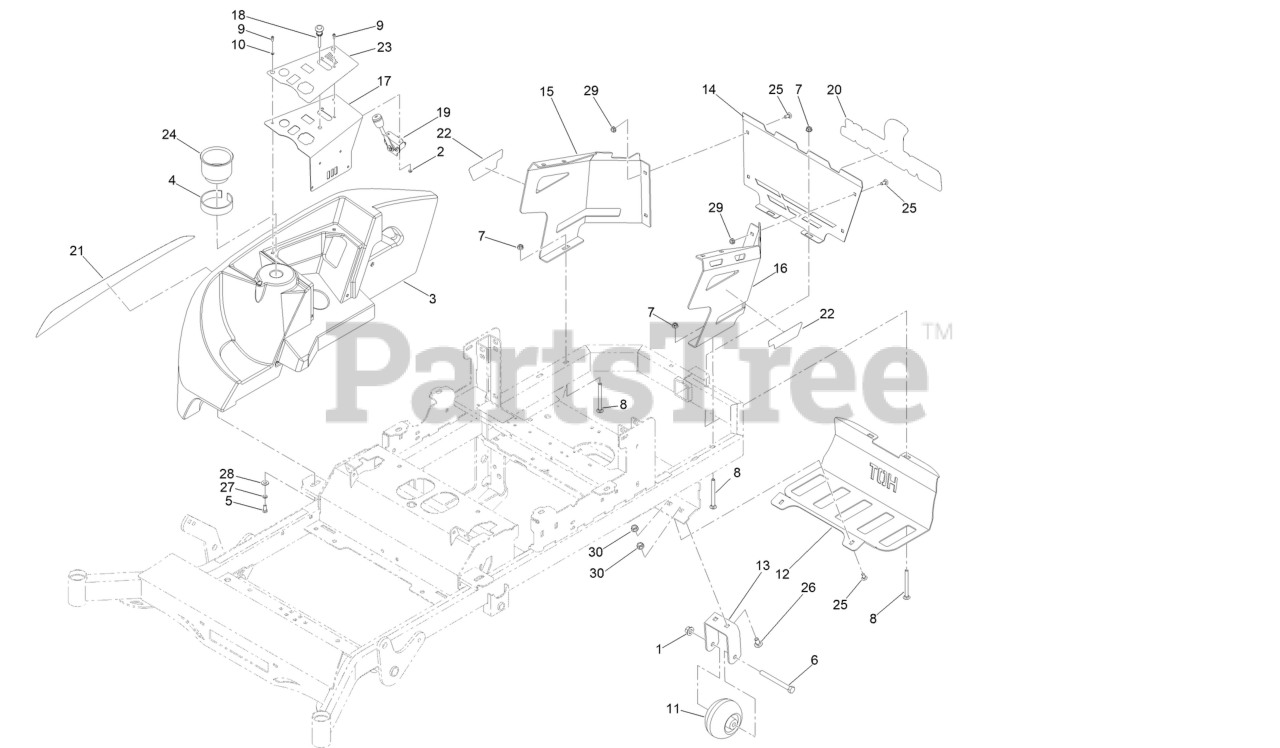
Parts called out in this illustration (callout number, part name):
1	NUT-LOCK
2	NUT-LOCK
3	CONSOLE W/ CUPHOLDER
4	TAPE-FOAM
5	SCREW-HH
6	SCREW-HH
8	3/8-16 X 4 CARRIAGE BOLT ZINC
9	10-24 X 1/2 SOCKET C/S 18-8 SS
10	#10 SPLIT LOCKWASHER 18-8 SS
11	MWR ANTI-SCALP WHL W/O GREASE FITTING
12	MWR MUFFLER GUARD PAINT
13	MWR STABILIZER MTG BRKT PAINT
14	PLATE - ENGINE COWLING
15	2021 RT/SRT ENGN COWLING RTPAINTED
16	2021 RT/SRT ENGN COWLING LT PAINTED
17	CONTROL PANEL BRKT INDIV CONTROLS PAINT
18	MWR CHOKE CABLE ASSM
19	KAWASAKI EFI THROTTLE
20	MWR RR SPARTAN LOGO
21	MWR FUEL TANK LOGO RT SIDE
22	SRT-XD MODEL DECAL
23	EFI KEYSWITCH CONSOLE DECAL
24	CUP HOLDER
25	BOLT-CARR
26	SCREW-CARR
27	WASHER-LOCK
28	WASHER-FLAT
30	NUT-HF
